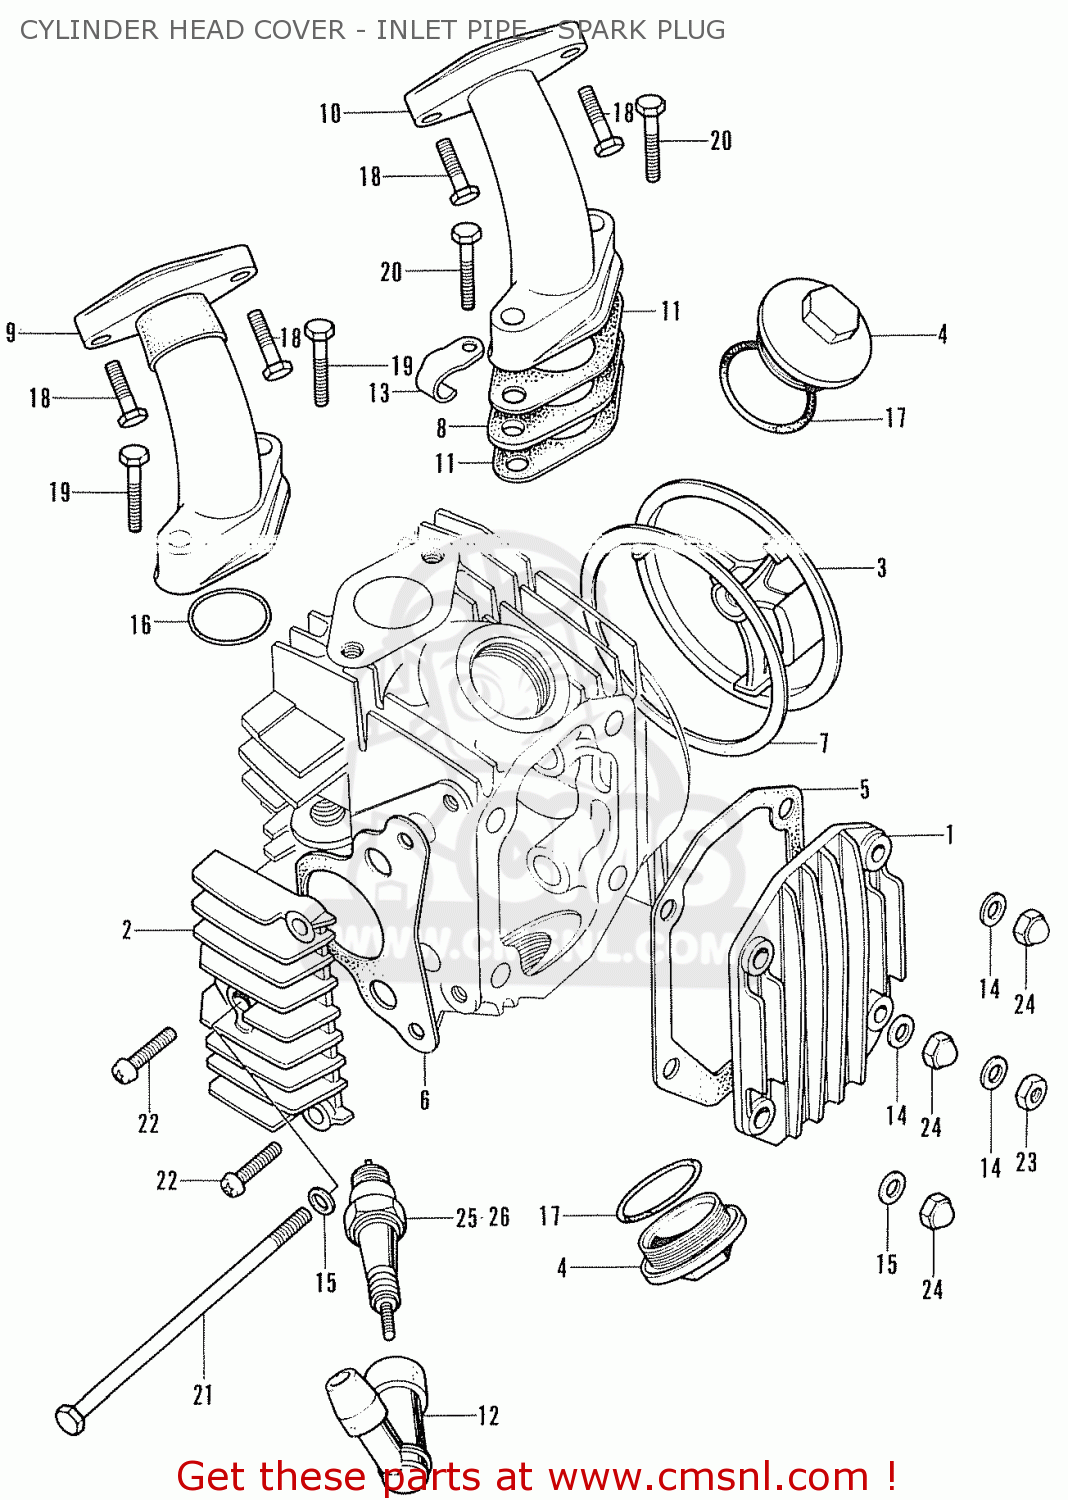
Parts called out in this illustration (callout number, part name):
1	COVER, CYLN. HEAD
2	COVER, CYLN. HEAD
3	COVER, CYLN. HEAD
4	CAP, TAPPET
5	GASKET (MCA)
6	GASKET (MCA)
7	GASKET (MCA)
8	INSULATOR,CARBU
9	PIPE,INLET
11	GASKET
12	CAP
14	WASHER, SEALING
15	WASHER A, SEALING
16	O RING, 24.5X2
17	O RING, 30.8M/M
18	BOLT,HEX 6X20
19	BOLT, HEX., 6X26
20	BOLT,HEX 6X36
21	BOLT HEX 6X112
22	SCREW CROSS 6X18
23	NUT,HEX 6MM
24	NUT, BLIND, 6M/M
26	PLUG,SPARK C-7HS
